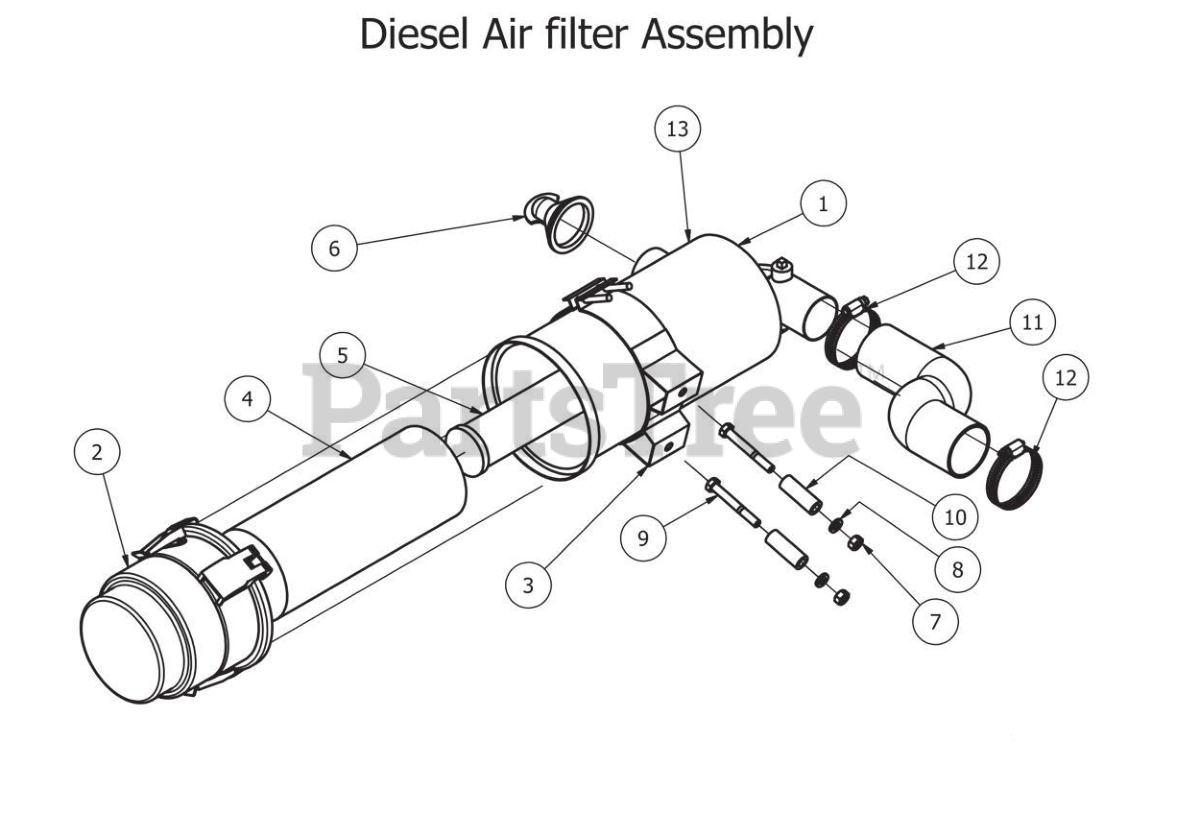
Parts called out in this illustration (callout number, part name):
1	Canister for All Diesel Models
2	Enginaire Air canister cap
3	Mounting Bracket For Diesel Air Filter
4	Diesel Air Filter- Outer
5	Diesel Air Filter- Inner
6	Debris Plug-Enginaire Filter
8	5/16" Lock Washer
9	5/16" x 2 1/2" Bolt
10	.378 x .625x 1.750 Spacer Zinc
11	Air Intake Hose-Diesel Air Filter Canister
12	2-1/2" Hose Clamp
13	Enginaire Canister VLR-Complete Assembly
